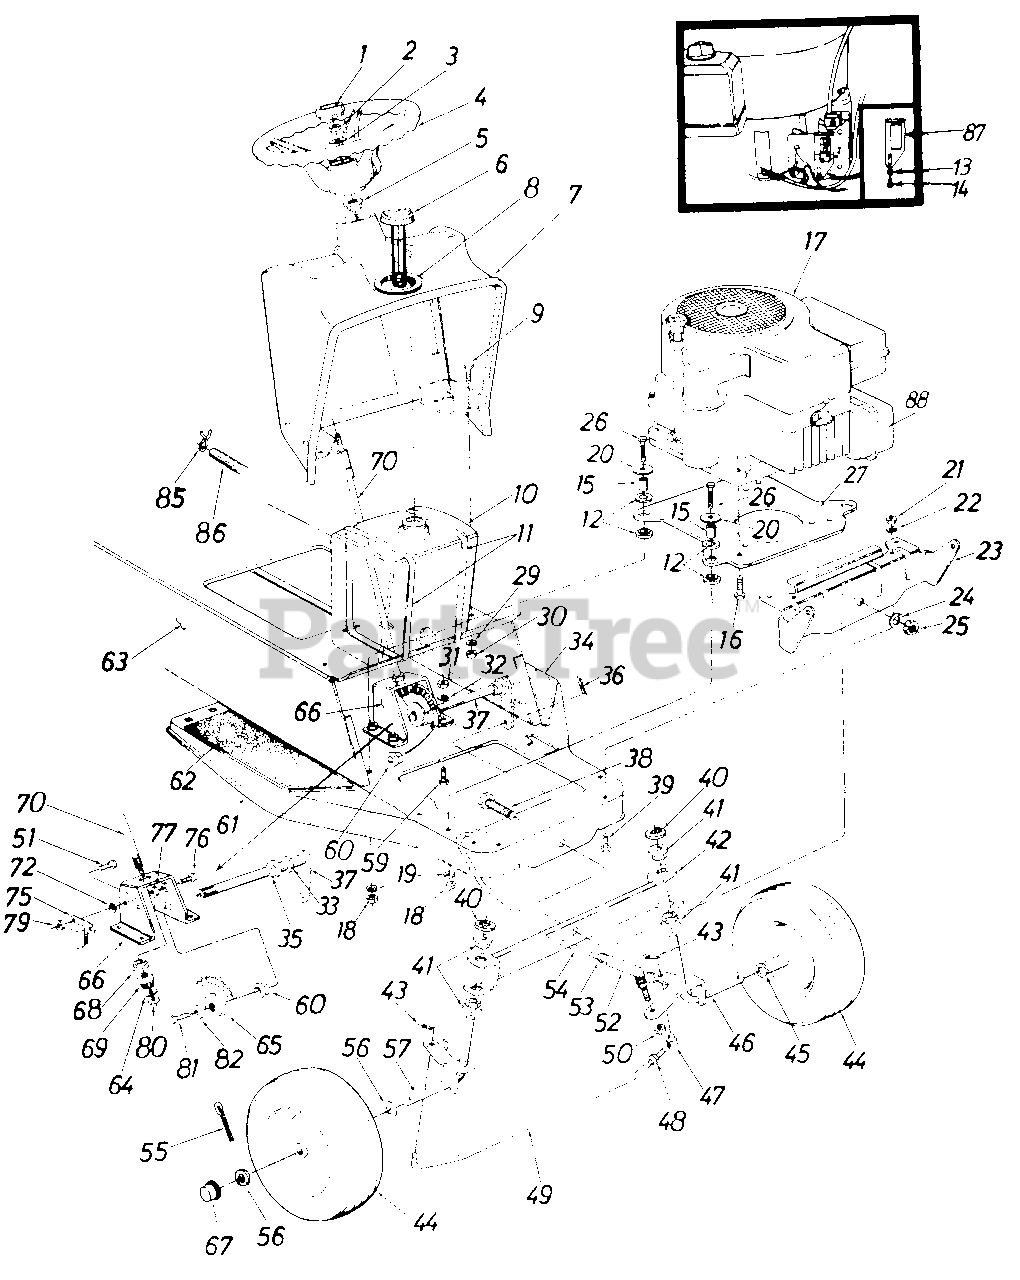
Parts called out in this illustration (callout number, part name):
1	Steering Wheel Cap
2	Hex Cent. L-Nut 5/16-18 Thd.
3	Bell-Wash. .345 I.D. x .88 O.D.
4	Steering Wheel
5	Hex Flange Bushing .63" I.D.
6	Fuel Gauge-Cap
7	Dash Panel Ass'y. w/Lights
8	Rubber Grommet
9	Hex Sems Scr. 1/4-20 x .75" Lg.
10	Fuel Tank
11	Cable Tie
12	Engine Mounting Grommet
13	Fl-Wash. .218" I.D. x .62"
14	Hex Sems Scr. #10-32 x .62" Lg.
15	Spacer
16	Hex Wash. Hd. Self-Tap Scr. 3/8-16 x 1.0" Lg.
17	Engine
18	Hex Nut 5/16-24 Thd.
19	L-Wash. 5/16" I.D.*
20	Fl-Wash. .34" I.D. x 1.12" O.D. x .125
21	Hex Nut 5/16-18 Thd.
22	L-Wash. 5/16 I.D.
23	Front Pivot Bracket
24	L-Wash. 5/8" I.D.
25	Hex Cent. L-Nut 5/8-18 Thd.
26	Hex Bolt 5/16-24 x 1.25 H.T.
27	Engine Base Plate
29	L-Wash. 1/4" Scr.
30	Hex Nut 1/4-20 Thd.
31	Hex Nut 5/16-18 Thd.
32	L-Wash. 5/16" I.D.
33	Fl-Wash. .812" I.D. x 1.38" O.D. x .100
34	Foot Pad-L.H.
35	Flange Brg. w/Flats
36	Cotter Pin 3/32" Dia. x .75"
37	Steering Arm Ass'y.
38	Hex Bolt 5/8-18 x 1.62" Lg.
39	Hex Sems Bolt 5/16-18 x .75" Lg.*
40	Push Nut
41	Hex Flange Bushing .62" I.D.
42	Pivot Bar Ass'y.
43	Cotter Pin 1/8" Dia. x .75" Lg.
44	Front Wheel Ass'y.-
45	Flange Bearing
46	Front Axle Ass'y.-L.H.
47	Pivot Bushing
48	Hex Jam Nut 3/8-24 Thd.
49	Tie Rod
50	Hex Ins. L-Nut 3/8-24 Thd.
51	Hex Bolt 1/4-29 x .5" Lg.
52	Ball Joint Ass'y.
53	Hex Jam Nut 3/8-24 Thd.
54	Drag Link
55	Cotter Pin 1/8 Dia. x 1.25" Lg.
56	Fl-Wash. .63" I.D. x 1.12" O.D. x .10"
57	Front Axle Ass'y.-R.H.
59	Hex Sems Scr. 5/16-18 x .75" Lg.
60	Flange Brg. w/Flats
61	Front Frame Ass'y.
62	Foot Pad-R.H.
63	Rear Frame
64	Fl-Wash. 5/16" I.D.
65	Side Gear
66	Steering Gear Support Ass'y.
67	Hub Cap
68	Hex Flange Bushing .50" I.D.
69	Pinion Gear
70	Steering Shaft
72	Ext. L-Wash. 1/4" I.D.
75	Solenoid
76	Hex Bolt Nylon 3/8-16 x 1.25" Lg.
77	Hex Cent. L-Nut 3/8-16 Thd.
79	Hex Nut 1/4-20 Thd.
80	Hex Cent. L-Nut 5/16-24 Thd.
81	Hex Bolt 3/8-24 x 75n Lg.
82	Bell-Wash.
85	Hose Clamps
86	Fuel Line 15" Lg.
87	Throttle Limiter
88	Muffler
